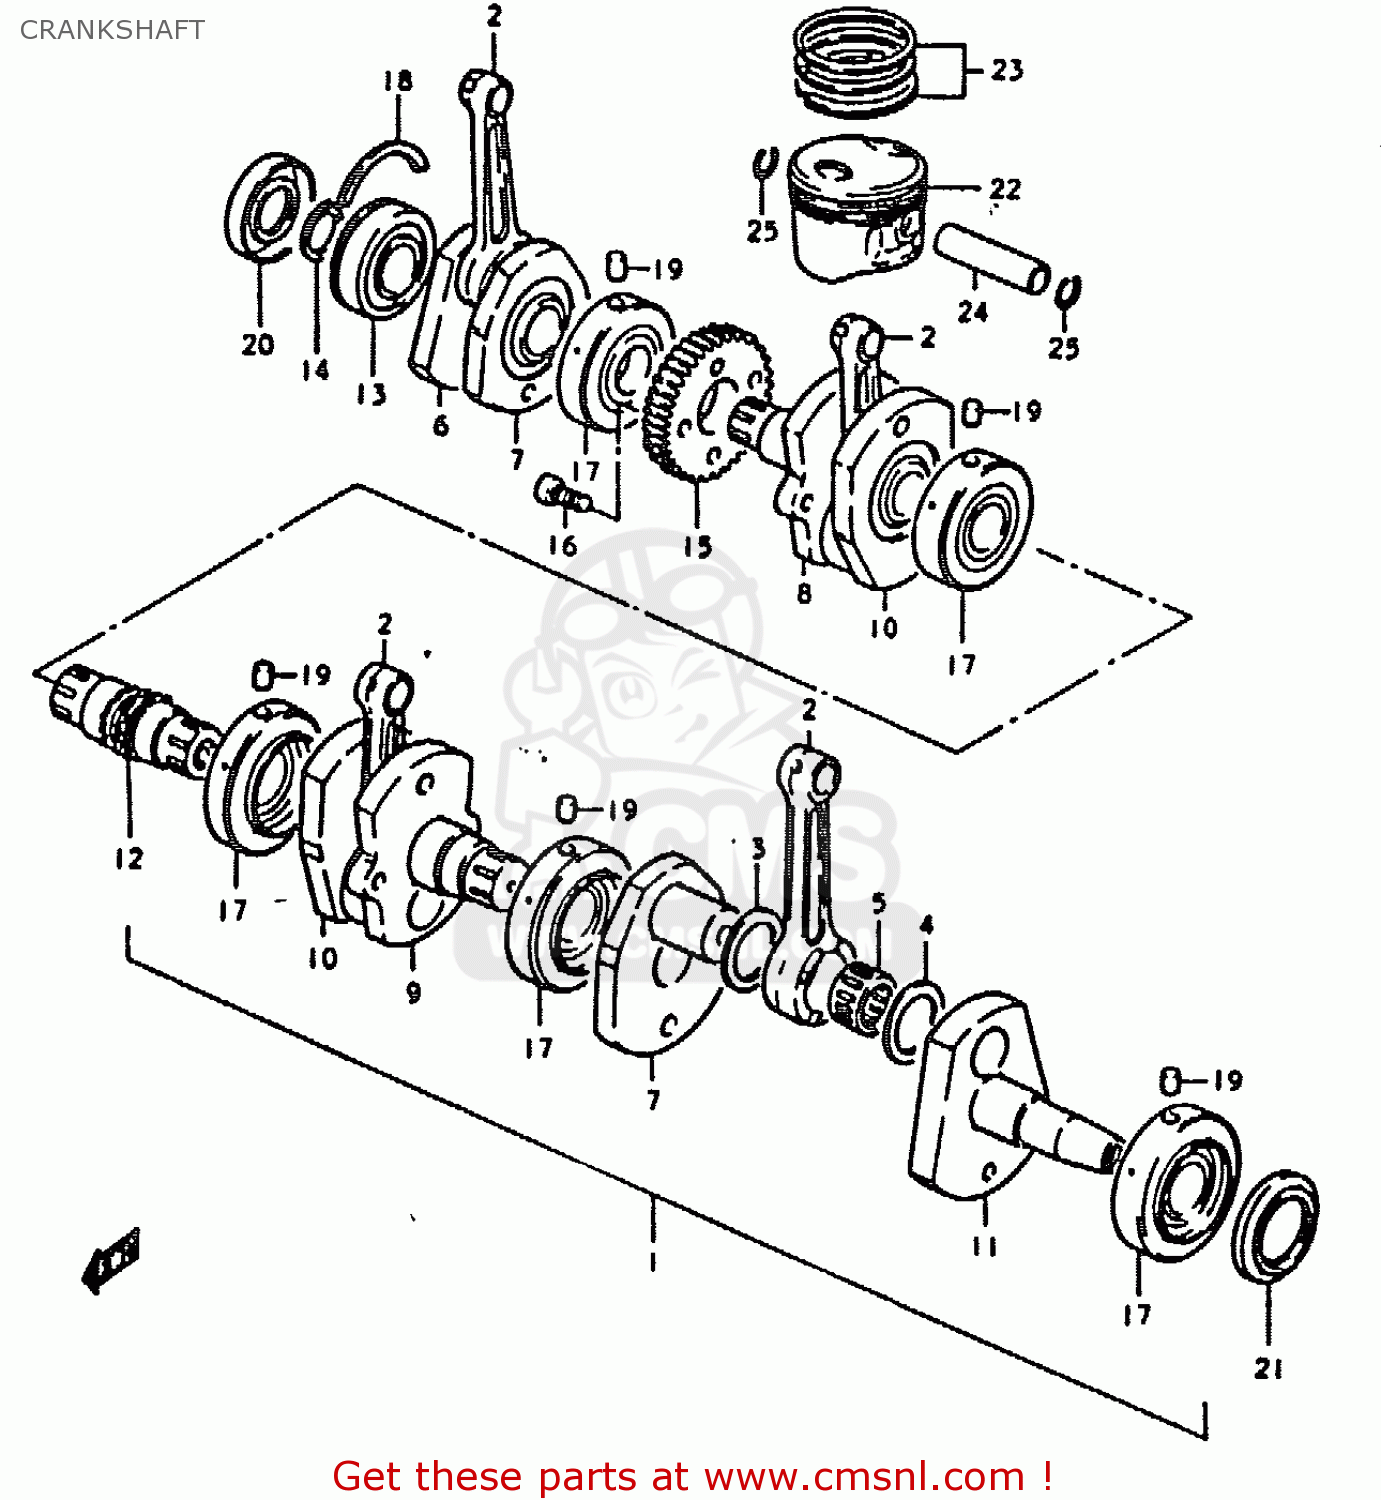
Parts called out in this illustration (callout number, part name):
1	CRANKSHAFT ASSEMBLY
2	ROD,CONNECTING
3	WASHER (29X48X2)
4	WASHER (29X48X1)
5	BEARING(29X39X20)
6	CRANKSHAFT
7	WEB,CRANK
8	CRANKSHAFT
9	CRANKSHAFT
10	WEB,CRANK,MIDDLE
11	CRANKSHAFT,LEFT
12	SHAFT,TIMING CHAIN DRIVE
13	BEARING(30X72X19)
14	CIRCLIP,30MM
15	GEAR,PRIMARY DRIVE
16	BOLT
17	BEARING
18	C RING
19	PIN
20	SEAL,OIL(30X72X11)
21	SEAL,OIL(47.3X60X6.5)
22	PISTON
23	RING SET,PISTON
24	PIN,PISTON (18MM)
25	CIRCLIP,PISTON PIN
